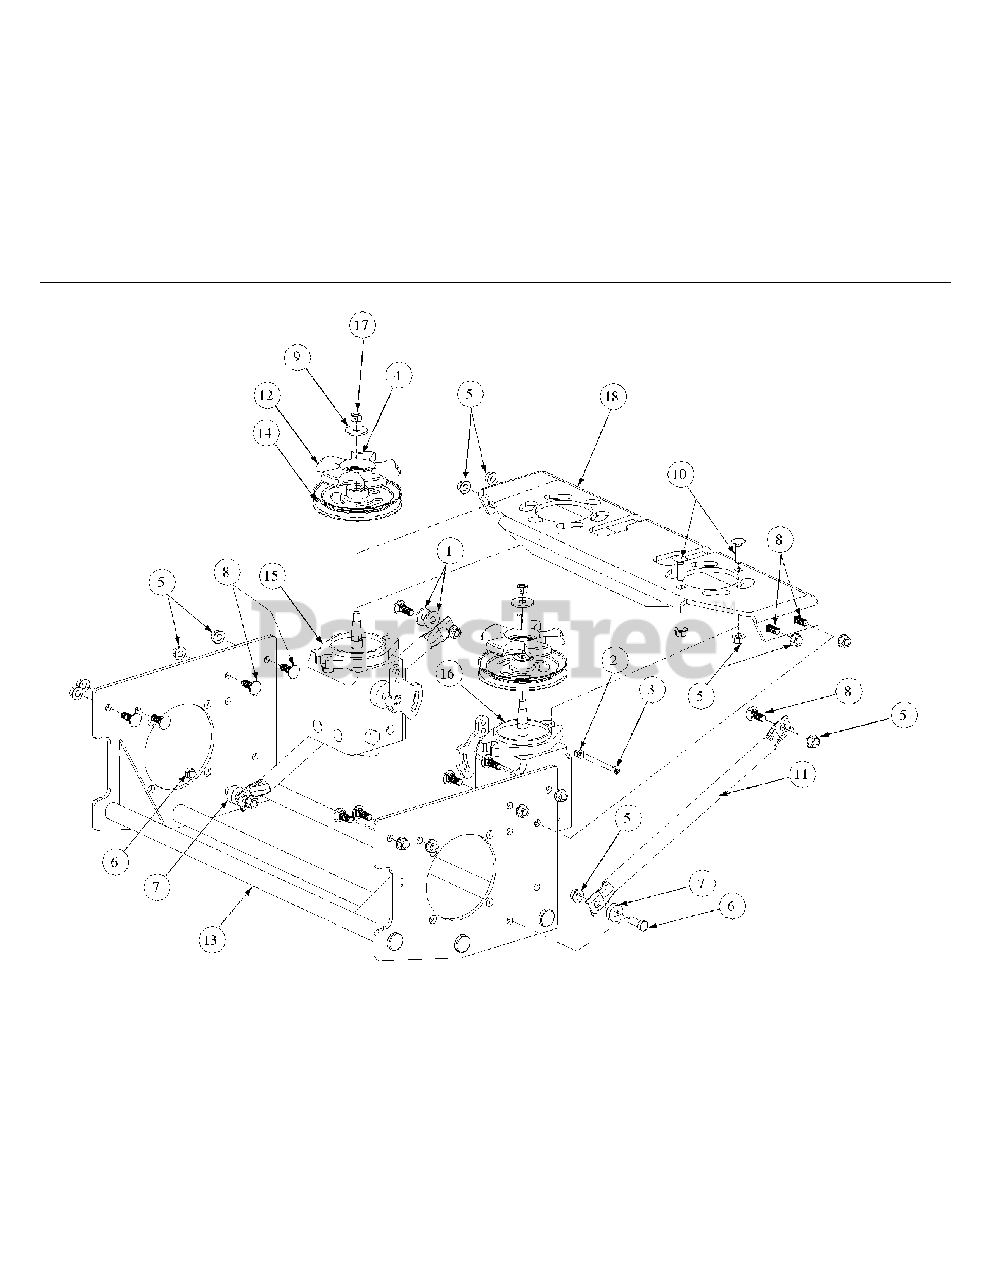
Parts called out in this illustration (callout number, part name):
1	Washer lock 3/8 zinc
2	Lock Nut, Nylon Insert, 1/4-20
3	Socket Head Cap Screw, 1/4-20 x 2-1/2
4	Key, 3/16" x 7/8"
5	Flange Lock Hex Nut, 3/8-16
6	Hex Cap Screw, 2/8 -16 x 1.25
7	Spacer, .406 ID x 1.00 OD x .38
8	Carriage Bolt, 3/8-16 x 1
9	Flat Washer, .411 x 1.25 x .100
10	Carriage Screw, 3/8-16 x 1.25
12	Hydro Pulley Fan
13	Hydro Motor Frame Assembly
14	Hydro Pulley Pump
15	Hydro Pump, LH
16	Hydro Pump, RH
17	Hex Nut, 3/8-24
18	Hydro Pump Mounting Weldment
